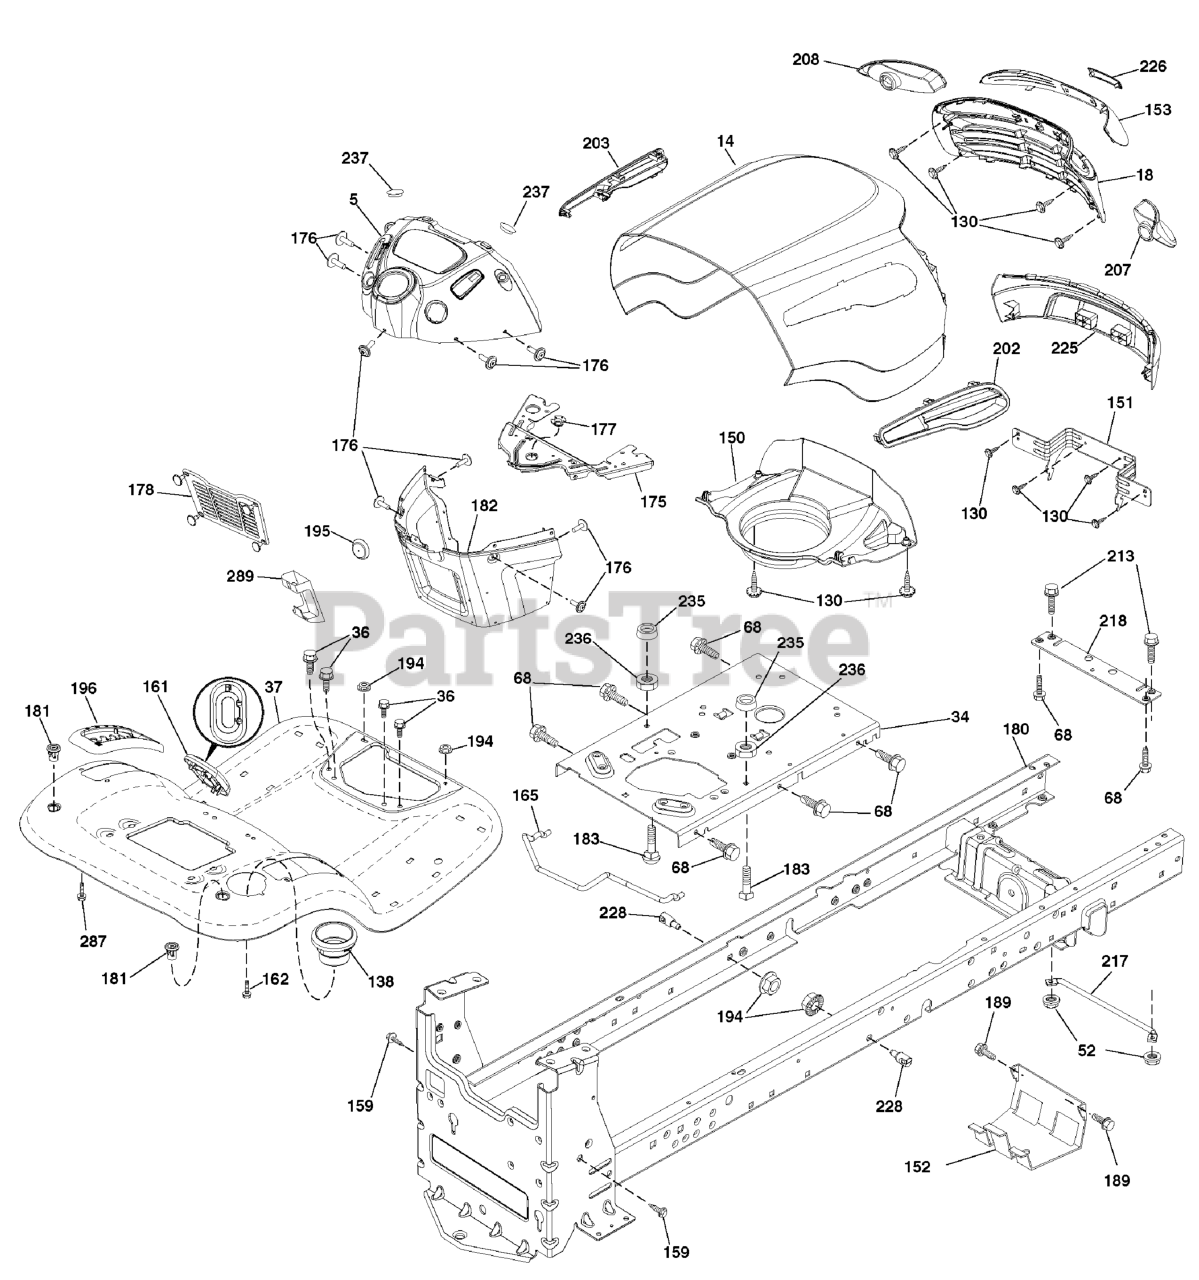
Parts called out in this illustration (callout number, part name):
34	Plate Engine
36	Screw 5/16-18 x 3/4
52	Nut Crown Lock 5/16-18
68	Screw Thdrol 5/16-18 x 1/2
130	Screw #10 x 0.750
138	Cupholder
150	Duct Heat Hood
151	Bracket Pivot
152	Shield Browning
159	Screw Hexwsh Thdrol 3/8-16 x 3/4
161	Window Fuel
162	Screw Hex Wsh Hi-Lo 1/4 x 1/2
165	Support Tank Rear
175	Crossmember
176	Screw 10-24 x 5/8 Wshd Qdrx
177	Bushing Steering
178	Cargo Asm. Net
180	Chassis
181	Bushing Mtg. Fender Crgo.
182	Dash Lower
183	Bolt Fin Hex 5/16-18 x 1-1/4 Full Thread
189	Screw 5/16-18 x 3/4
194	Nut Lock Hex Flange 5/16-18
195	Plug Hold Dash
196	Console Asm. Deck Lift
202	Side Vent RH
203	Side Vent LH
207	Bezel RH
208	Bezel LH
213	Bolt Hex HD 5/16-18 unc x 3/4
217	Rod Pivot Chassis
218	X-Piece Hood Stop
228	Stud Fastener
235	Spacer Fender
236	Nut Center Lock 5/16-18
237	Plug Mount Cargo
287	Screw hex 1/4-20 x 3/8
289	Plug Cruise/Phone
